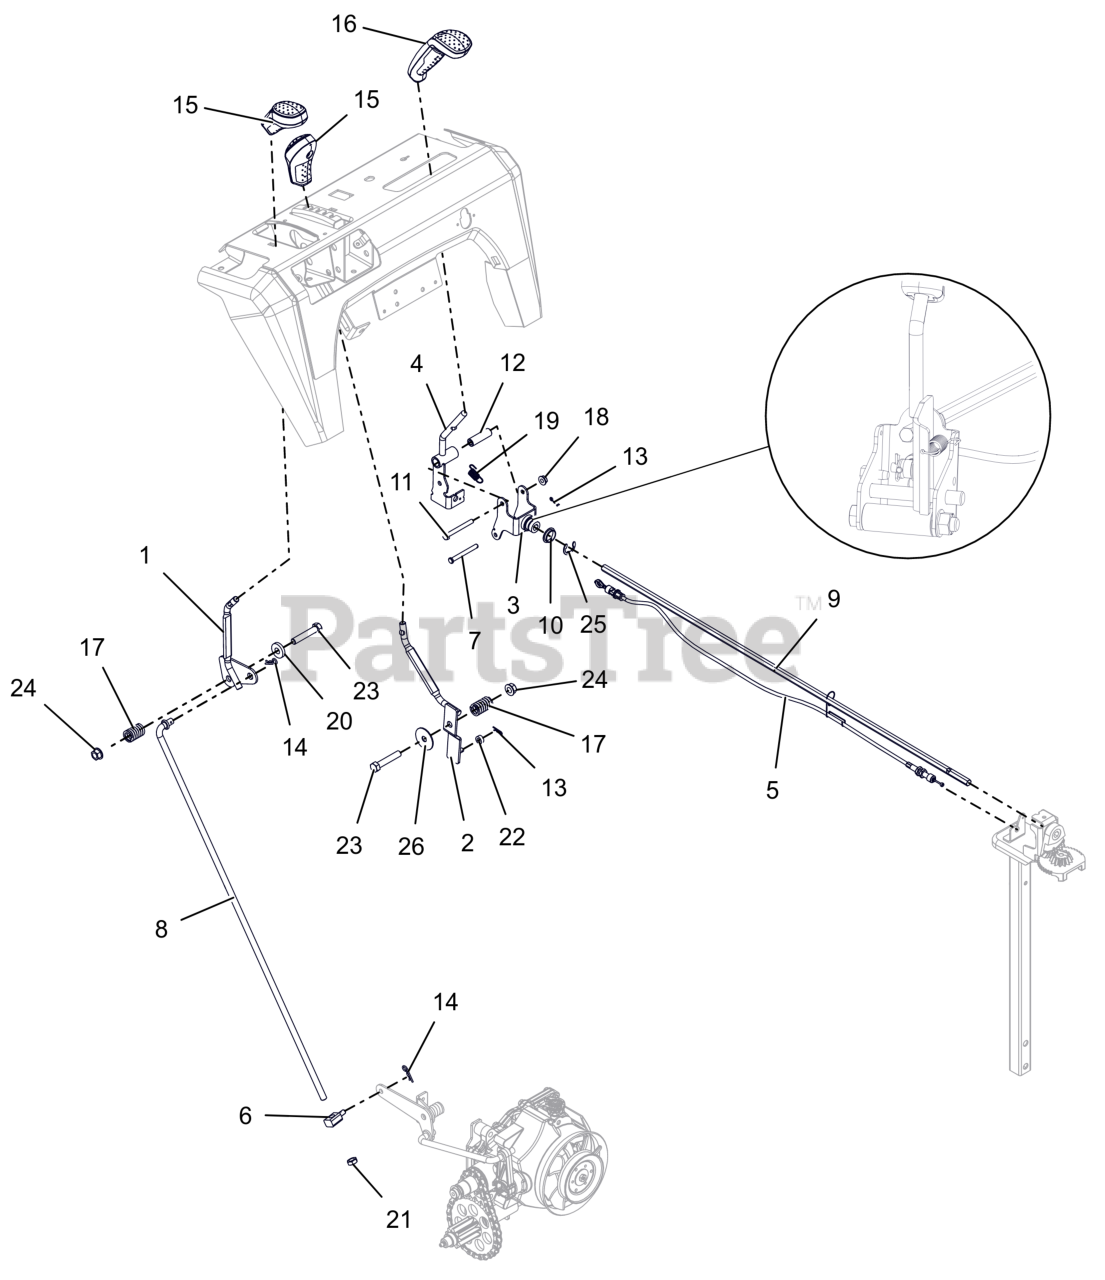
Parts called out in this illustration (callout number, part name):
1	WELDMENT,LG DASH SPEED CONTROL
2	WELDMENT,LG DASH DEFL CONTROL
3	WELDMENT, CONTROL BRACKET
4	WELDMENT, CONTROL LEVER
5	CABLE, CHUTE LOCK, PRO
6	PIVOT,SHIFT ROD .375-16(TRUNN)
7	PIN, CLEVIS - .25 X 2.25 ZCC
8	ROD, SHIFT-PRO
9	ROD, HEX - CHUTE ROTATION
10	BUSHING, POLYLINER-.75 SNAPIN
11	BLT,HEX .25-20X2.25 G5 ZCC
12	BSHG, SLV .265X.505X1.665
13	PIN, HAIR #178 .06X.77 ZCC
14	PIN, HAIR #213 .08X1.19 ZCC
15	KNOB, CONTROL, DASH
16	HANDLE, QUICK TURN, ASM
17	SG-COMP .125X.781X1.250
18	NUT-LK-CTR-FLG .25-20 ZC120
19	SPRING-EXT .047X.438X1.45
20	WSHR, FLT .406X1.00X.188 ZCC
21	NUT-JAM .375-16 G2 ZCC
22	BSHG-SLV .265X.500X.219
23	BLT,HEX .38-16X2.00 G5 ZCC
24	NUT-LK-TOP-FLG .38-16 ZC120
25	E-RING .750X.050
26	WSHR,FLT .380X1.50X.062 ZCC
